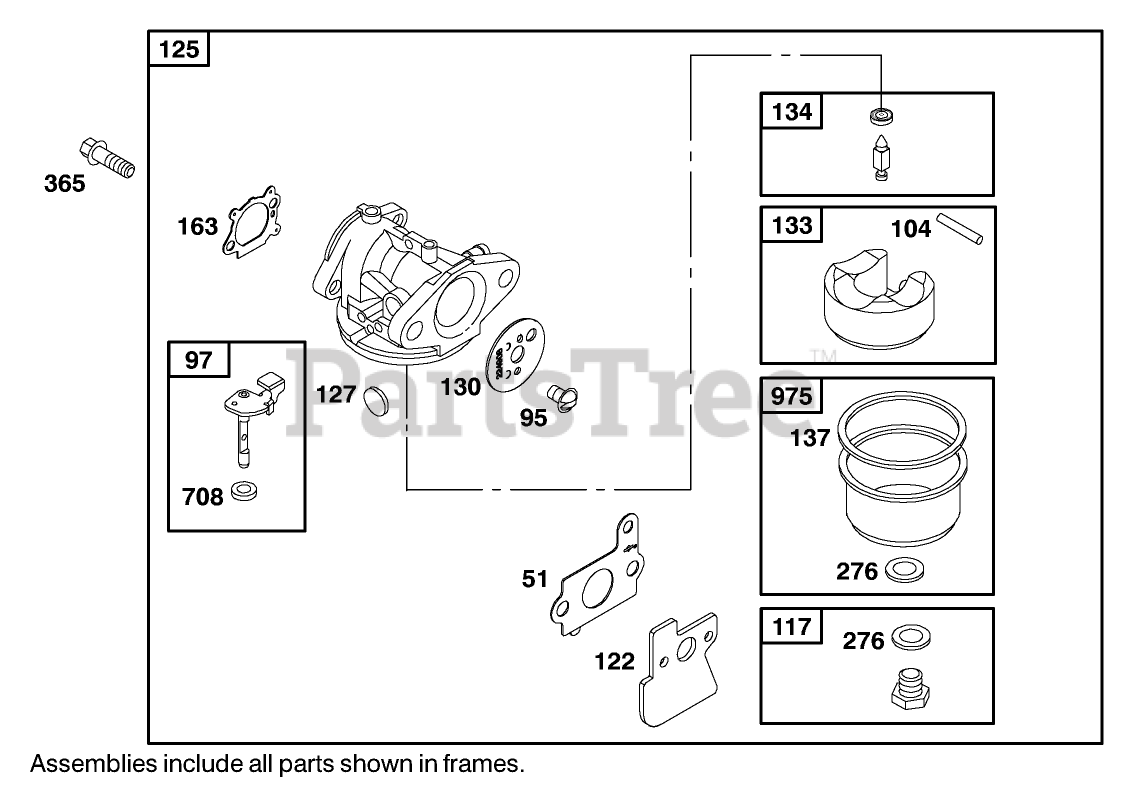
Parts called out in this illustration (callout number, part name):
51	Gasket-Intake
95	Valve-Choke
97	Shaft?Throttle
104	Pin-Hinge, Float
117	Jet-Main
122	Gasket-Intake
125	Carburetor
127	Welch Plug (Sold in Kit Only)
130	Valve?Throttle
133	Float-Carburetor
134	Valve-Inlet (Includes Seat)
137	Float Bowl Gasket (Sold in Kit Only)
163	Air Cleaner Gasket
276	Bowl Washer (Sold in Kit Only)
365	Screw
708	Seal-Shaft, Choke Throttle
975	Bowl-Float
